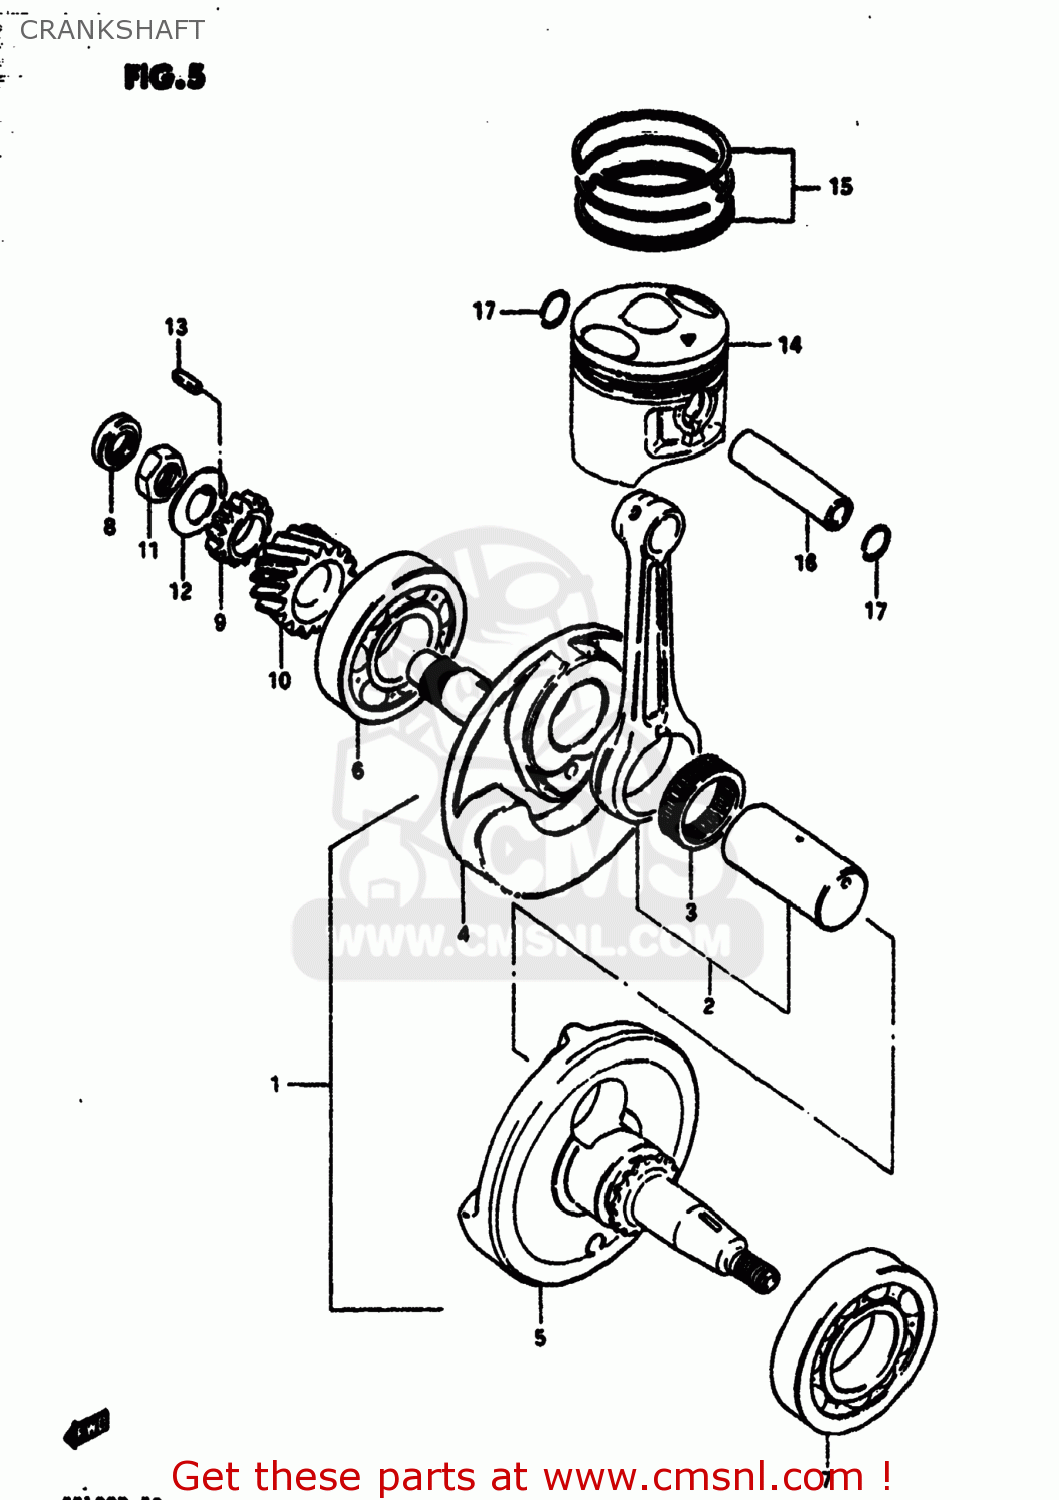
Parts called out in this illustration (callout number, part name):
1	CRANKSHAFT ASSEMBLY
2	CRANKSHAFT ASSEMBLY
3	BEARING
4	CRANKSHAFT,RIGHT
5	CRANKSHAFT,LEFT
6	BEARING,MIDDLE
7	BEARING,LEFT
8	OIL SEAL
9	GEAR,OIL PUMP DRIVE
10	GEAR,PRIMARY DRIVE
11	NUT
12	WASHER
13	KEY
14	PISTON (51.00MM)
15	RING SET,PISTON
16	RING,PISTON
17	RING,SNAP 14MM
